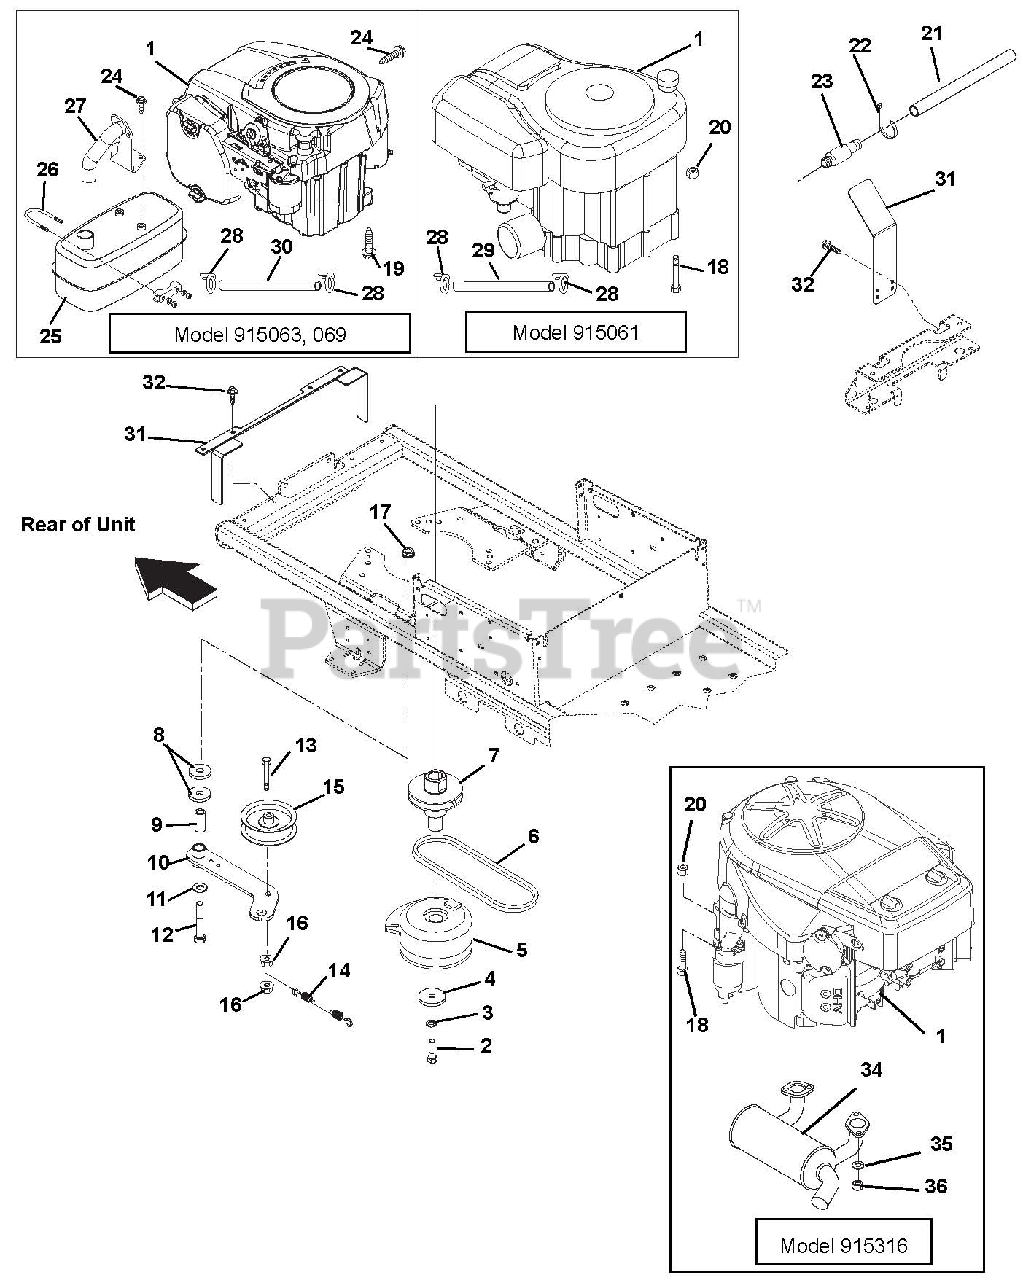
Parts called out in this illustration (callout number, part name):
1	ENGINE, 15HP KOLHER
1	ENGINE,28 CI B&S I/C
1	ENGINE, 15HP KAW FH451V
2	BLT-HEX .44-20X4.50 GR8 YWZC
3	@WSHR-LK .44X.109 REG YWZC
4	WSHR-FL-STL .469X2.00X.25 YWZC
5	ELECTRIC CLUTCH/BRAKE (3.4AMP)
6	V-BELT, HA-RAW EDGE
7	CRANKSHAFT EXTENSION
8	WSHR-FL-STL .515X1.625X.250 YZ
9	BSHG-SLV .500X.750X1.560
10	WMT,IDLER
11	@WSHR-FL-STL.531X1.06X.095YWZC
12	@BLT-HEX .50-13X3.25 GR5 YWZC
13	@BLT-HEX .38-16X2.00 GR5 YWZC
14	SPRING, EXT
15	IDLER FLANGED 3.50
16	@NUT-LK-NYL-FLG .38-16 YWZC
17	@NUT-LK-TOP-FLG .50-13 YWZC
18	@BLT-HEX .31-18X1.75 GR5 YWZC
19	@SCR-TAP .38-16X1.00 HWH TR YZ
20	@NUT-LK-NYL-FLG .31-18 YWZC
21	TUBE, OIL DRAIN
22	CABLE TIE LG 5-1/2
23	VALVE, OIL DRAIN
24	@SCR-TAP .25-20X.50 HWH TR YWZ
25	MUFFLER, KOHLER COURAGE SINGLE
26	MUFFLER CLAMP
27	WMT, MANIFOLD
28	CLAMP-HOSE WIRE .490/.510X.116
29	GAS LINE-BULK 1/4" I.D.
30	GAS LINE-BULK 1/4" I.D.
31	HEAT SHIELD,MINI-Z
32	@SCR-TAP .31-18X.50 HWH TR YWZ
33	HEAT SHIELD
34	MUFFLER, KAW. (COMPACT-Z)
35	@WSHR-LK .31X.078 REG YWZC
36	NUT-HEX M8-1.25 YWZC
